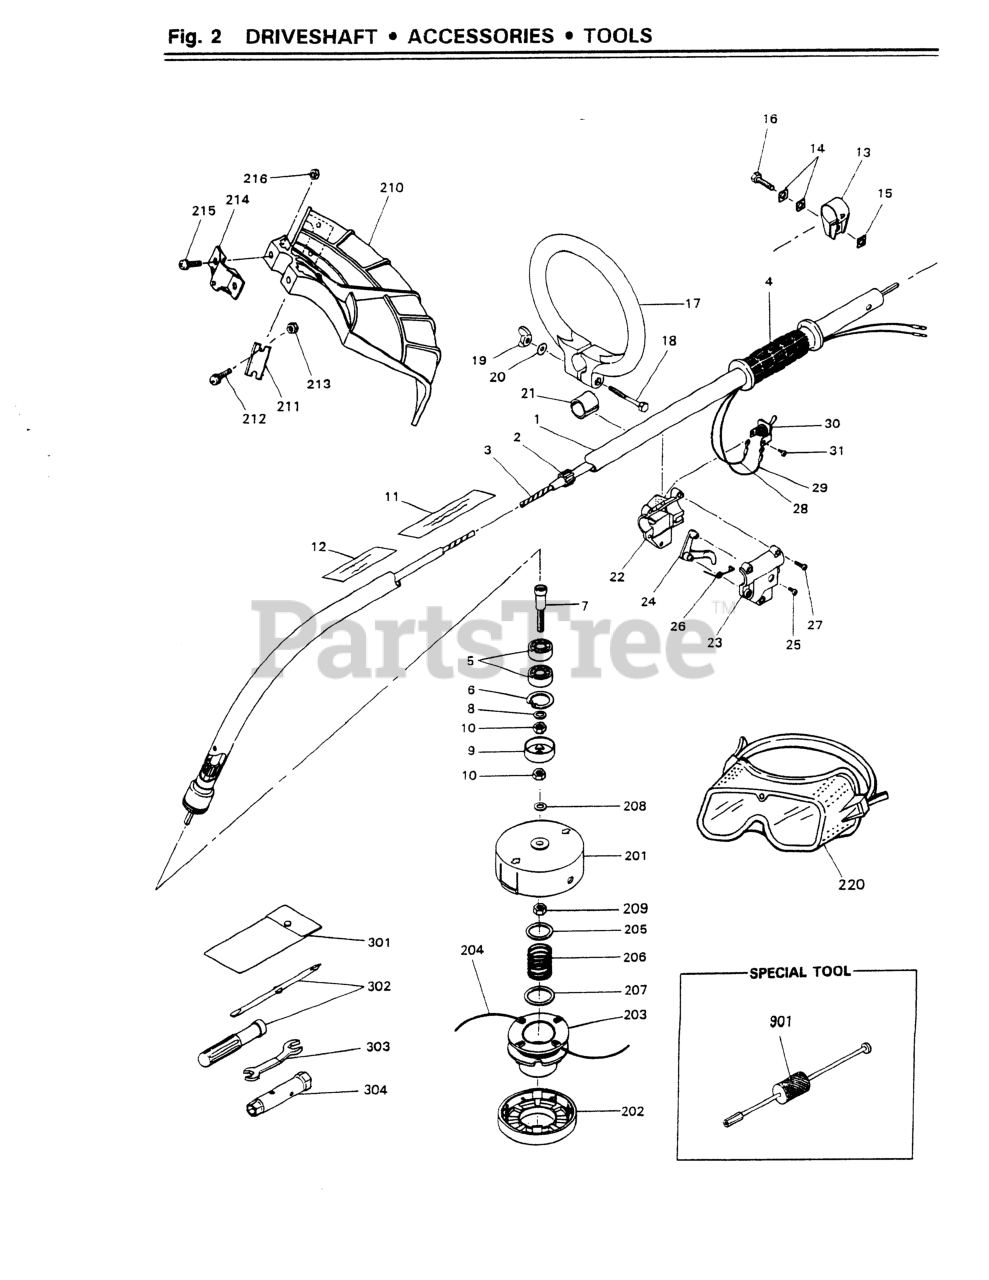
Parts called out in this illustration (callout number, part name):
3	SHAFT, FLEX (NO LONGER AVAIL)
6	RING, SNAP, M32 x 1.2
7	SHAFT (NO LONGER AVAILABLE)
8	WASHER, M8 x 16
9	COVER (NO LONGER AVAILABLE)
10	NUT, M8 x 6
11	PLATE, NAME
12	PLATE, CAUTION
16	BOLT, M6 x 35
18	BOLT, M6 X 50
19	NUT, WING
20	WASHER, M6 X 16
22	CASE (NO LONGER AVAILABLE)
23	CASE-L (NO LONGER AVAILABLE)
24	LEVER, THROTTLE (NLA)
25	SCREW, M5 X 6 (USE 0260-20508)
26	SPRING (NO LONGER AVAILABLE)
27	SCREW, HOUSING
28	CORD (A) (NO LONGER AVAIL)
30	SWITCH
31	SCREW, M4 X 5
203	HOLDER, CORD
205	PLATE, LARGE
207	PLATE, SMALL
208	WASHER, M8 x 16
212	SCREW, M4 X 12
214	CLAMP (NO LONGER AVAILABLE)
216	NUT, M6 X 5
302	SCREWDRIVER
